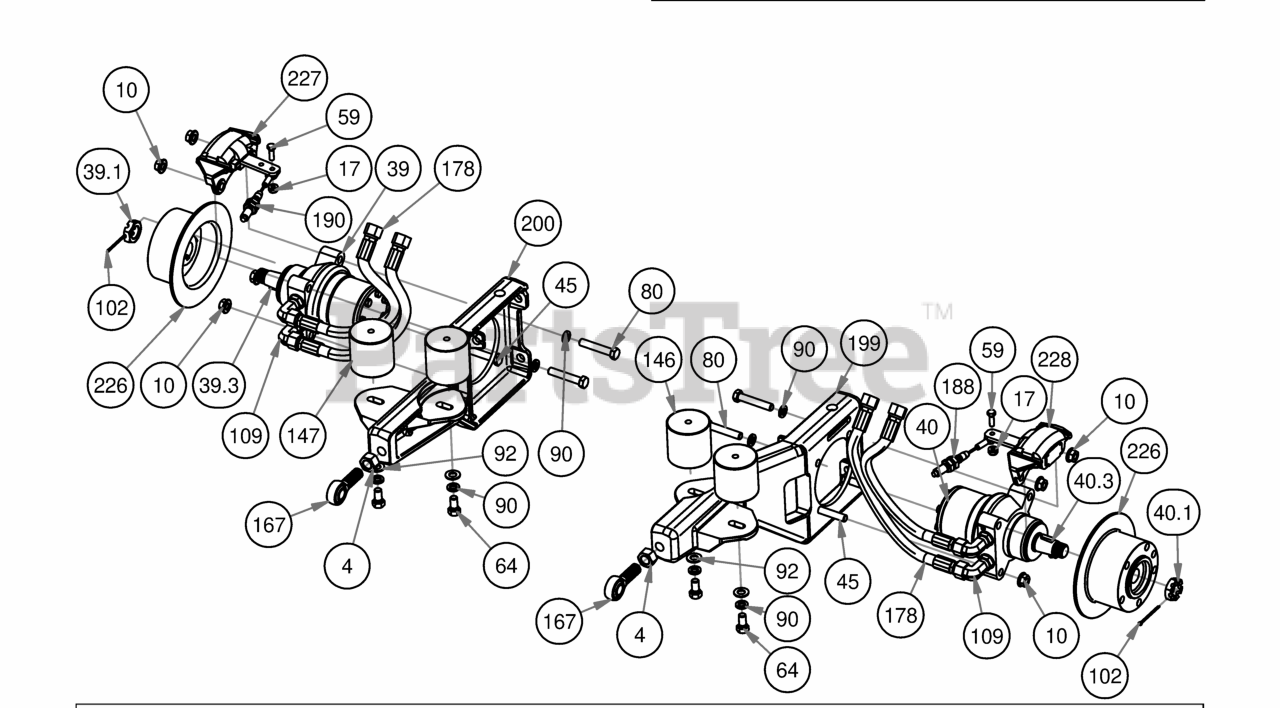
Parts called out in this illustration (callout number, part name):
4	3/4"-16 Fine Full Nut
5	3/4" Course Thread Nylon Lock Nut
10	1/2" Flange Nut
11	3/8" Hex Nut
13	1/2" Hex Nut
14	5/8 Std NC Nylock Nut
17	5/16-18 Nylon Flange Nut
39	18cc Parker Wheel Motor- Right
39.1	1" Castle Nut for Wheel Motor
39.3	Woodruff Key
40	18cc Parker Wheel Motor- Left
40.1	1" Castle Nut for Wheel Motor
40.3	Woodruff Key
45	1/2" x 3" Hex Bolt
46	M6-1.0 X 16MM Hex Bolt
50	3/4 x 2 1/2 Course Thread Bolt
51	AS 2465 - 5/8 x 2 3/4 UNC
57	All Thread-Pump Idler Tensioner
59	5/16" x 1" Bolt
64	1/2" x 1" Hex Bolt
69	1/2" Nylcock Nut (1/2 Jam)
79	3/8 x 1.5" Bolt
80	1/2" x 2 3/4" Hex Bolt
82	5/8" x 2 1/2" Grade 5 Hex Bolt (Coarse)
84	1/2-20 x 1-1/2 Lug Bolts Zinc
88	5/8" Flat Washer SAE Spec Grade 8
89	1/4" Lock Washer
90	1/2" Lock Washer
91	3/8" Lock Washer
92	1/2" Washer (Grade 8)
96	1/4" Flat Washer
98	5/16" Flat Washer
102	1/8x2-1/4 cotter pin Zinc
104	2019 Assy-26x12-12 Reaper Turf -10.5" Rim
105	2019 Assy-26x12-12 Reaper Turf-8.5" Rim
107	ZT Fitting, 3/8 x 3/8 45 Degree, 4603-6-6
108	2019 Outlaw 45 Degree Pump Fitting #6802-10-08
109	2019 Rouge/Renegade Wheel Motor 90* Fitting #6801-10L
110	90 Degree Fitting, 1/2 x 3/4, 4601-8-8
115	Spacer 1.125OD x .625 ID x .250 Length
117	5/8" x 1/" Collar W/One Set Screw
146	Vibration Mount-Blue Dot
147	Vibration Mount-Green Dot
148	5" Pump Pulley
151	Deck Idler Spring
153	2019 Rogue Pump Idler Assy
154	2019 Suspension Gusset Outlaw
158	5mm x 1.25" Key
165	2019 Suspension Radius Rod Assembly
166	2019 Suspension Radius Rod Assembly
167	3/4-16 RH Male Rod End
168	2019 Rogue/Renegade Left Pump 16cc
169	2019 Rogue/Renegade Right Pump 16cc
178	20" Hydraulic Hose
188	2019 Short Brake Cable-Suspension Models
190	2019 Long Brake Cable-Renegade, Rogue
199	2019 Left Trailing Arm
200	2019 Right Trailing Arm
203	2019 Veritical Suspension Frame
226	Brake Disk
227	XP/AOS Right Brake Caliper
228	XP/AOS Left Brake Caliper
